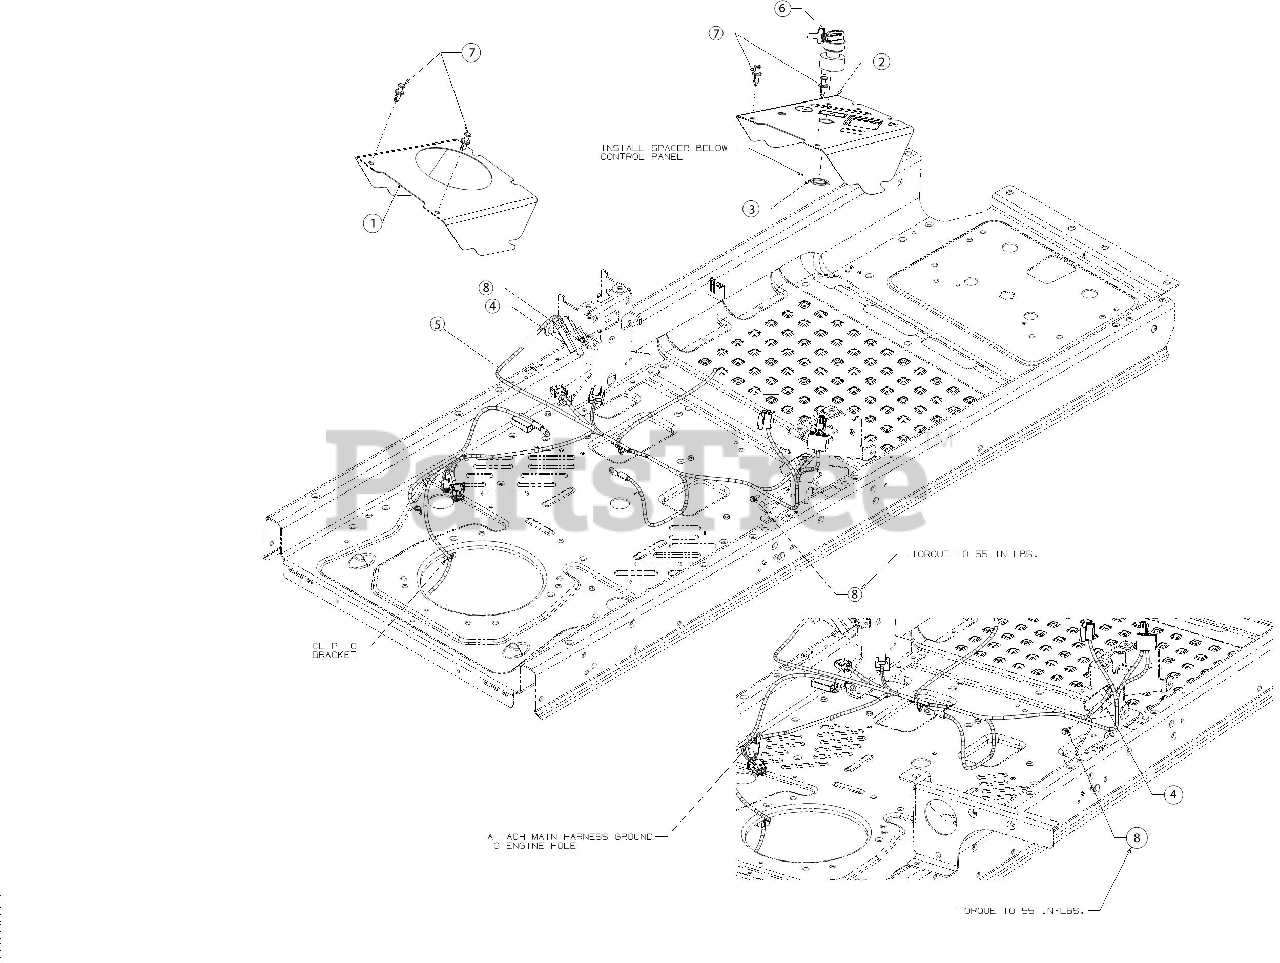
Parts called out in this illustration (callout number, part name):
3	IGNITION SWITCH SPACER
4	INTERLOCK SWITCH (NO/NC)
5	WIRING HARNESS
6	IGNITION SWITCH
7	PLASTIC RIVET
8	SHOULDER SCREW
